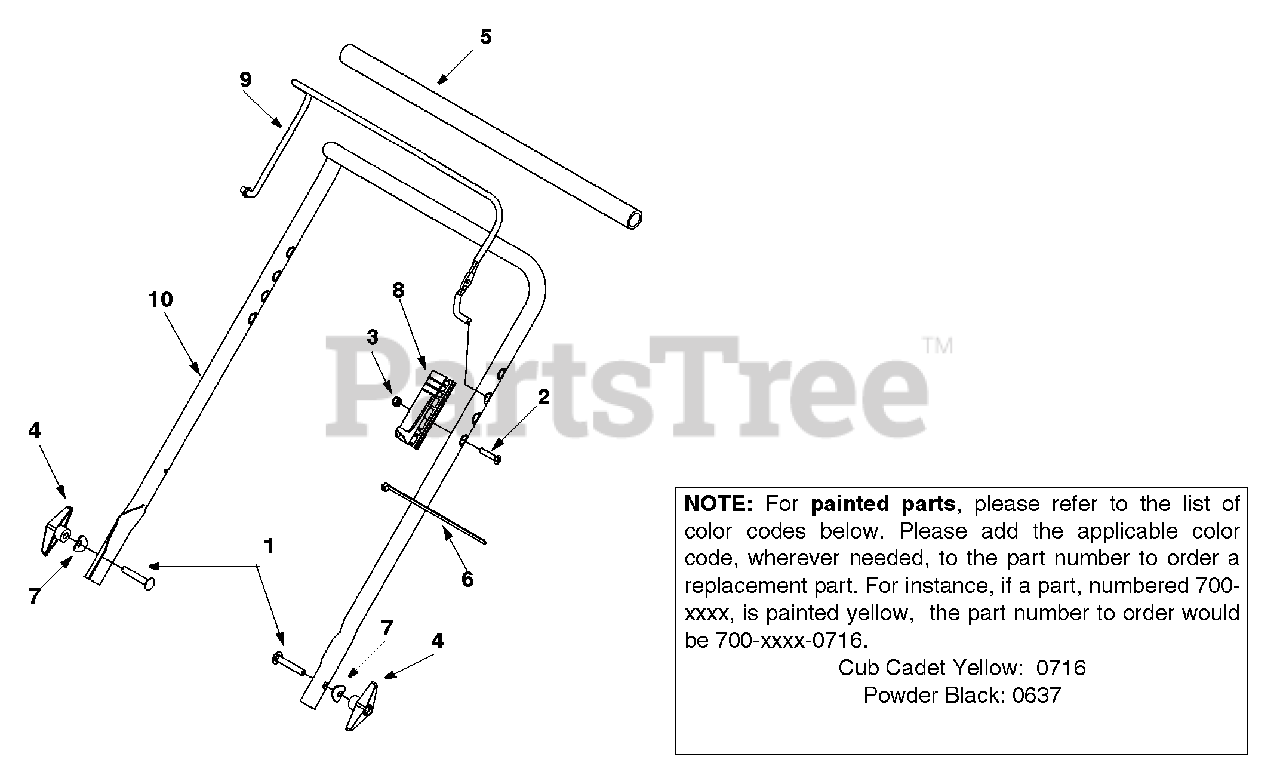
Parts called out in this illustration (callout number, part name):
1	Carriage Screw 5/16-18 x 2.0"
2	Machine Screw
3	Hex Lock Nut 1/4-20
4	Hand Knob w/ Wing Nut
5	Foam Grip
6	Cable Tie
7	Saddle Washer
8	Control Housing
